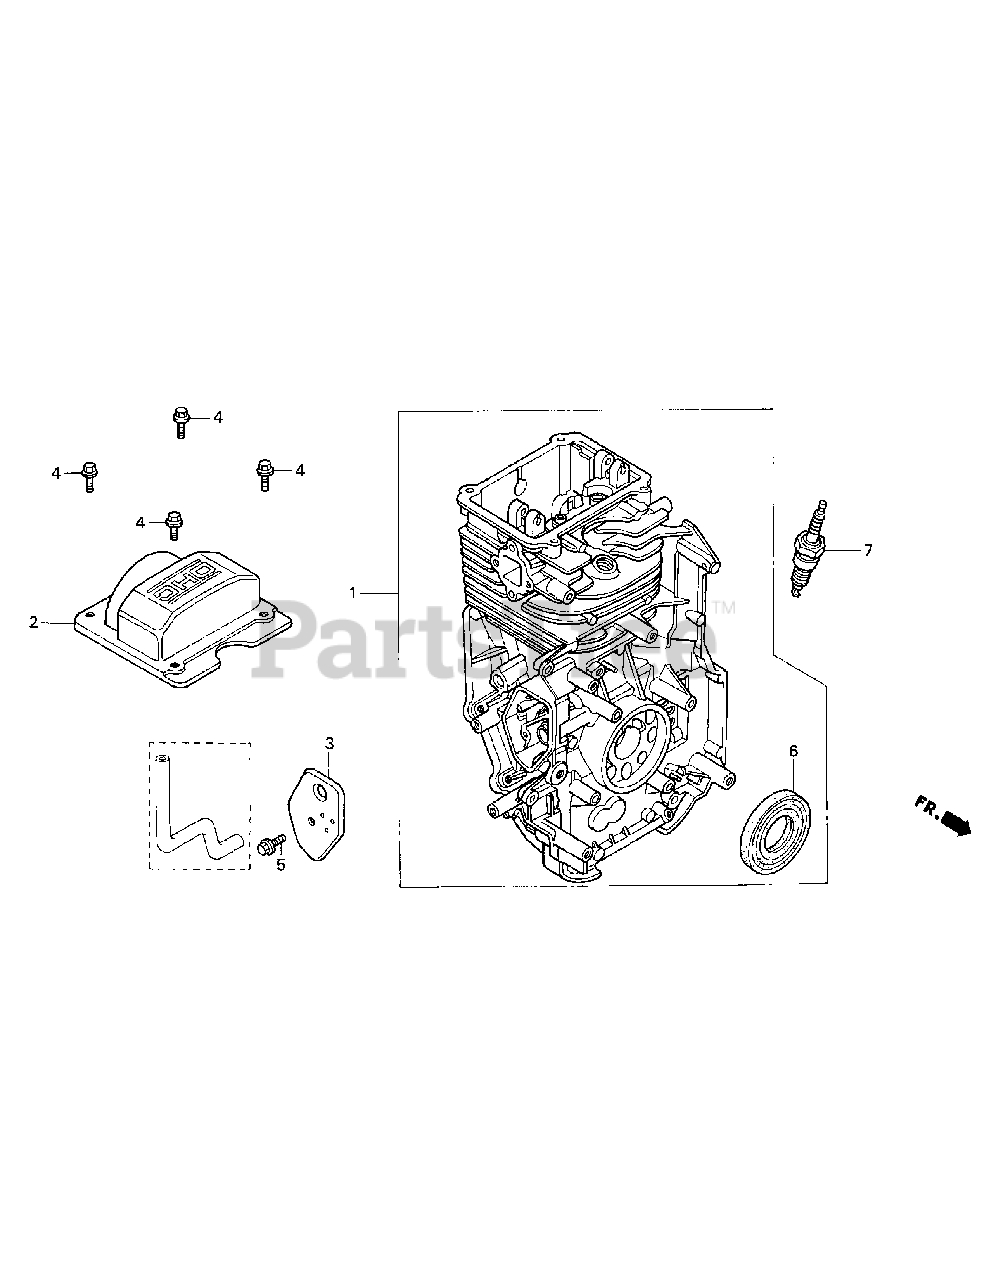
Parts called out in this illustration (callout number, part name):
1	Assembly, Cylinder
2	Seal, Valve Stem
3	Cover Complete, Cylinder Head
4	Cover Complete, Breather
5	Valve, Inlet
6	Valve, Exhaust
7	Spring, Valve
8	Retainer, Valve Spring
9	Bolt, Flange, 6 x 12 (CT200)
10	Bolt, Flange, 6 x 14 (CT200)
11	Oil Seal, 25.4 x 62 x 6
12	Plug Spark (BPR6ES) (NGK)
